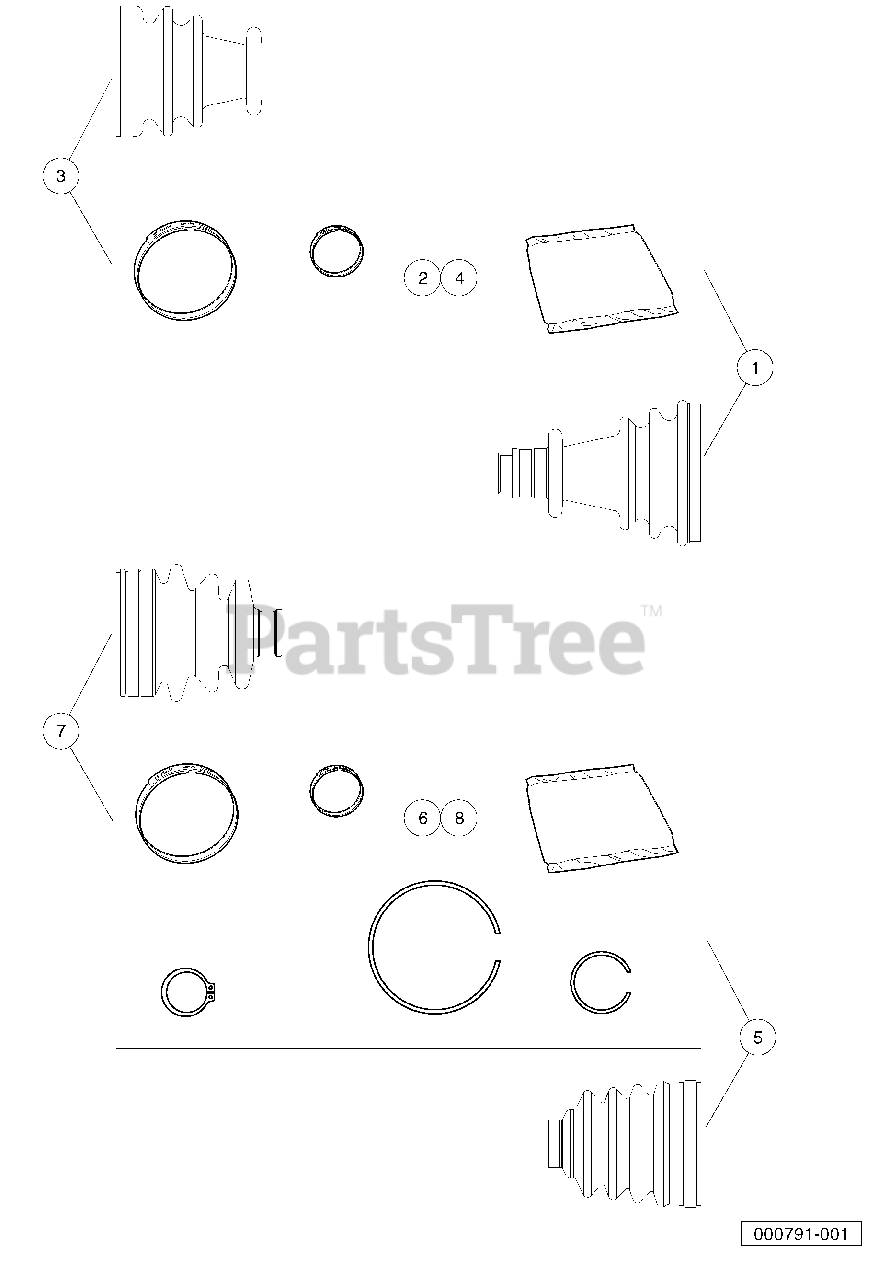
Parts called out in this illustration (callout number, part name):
1	Boxed Outboard Boot Kit
2	Half Shaft Boot Instl. Instr.
3	Boxed Inboard Boot Kit
4	Half Shaft Boot Instl. Instr.
5	Kit, Outer Boot, Gen 2
6	Instructions, Boot Replacement
7	Kit, Inner Boot, Gen 2
8	Instructions, Boot Replacement
